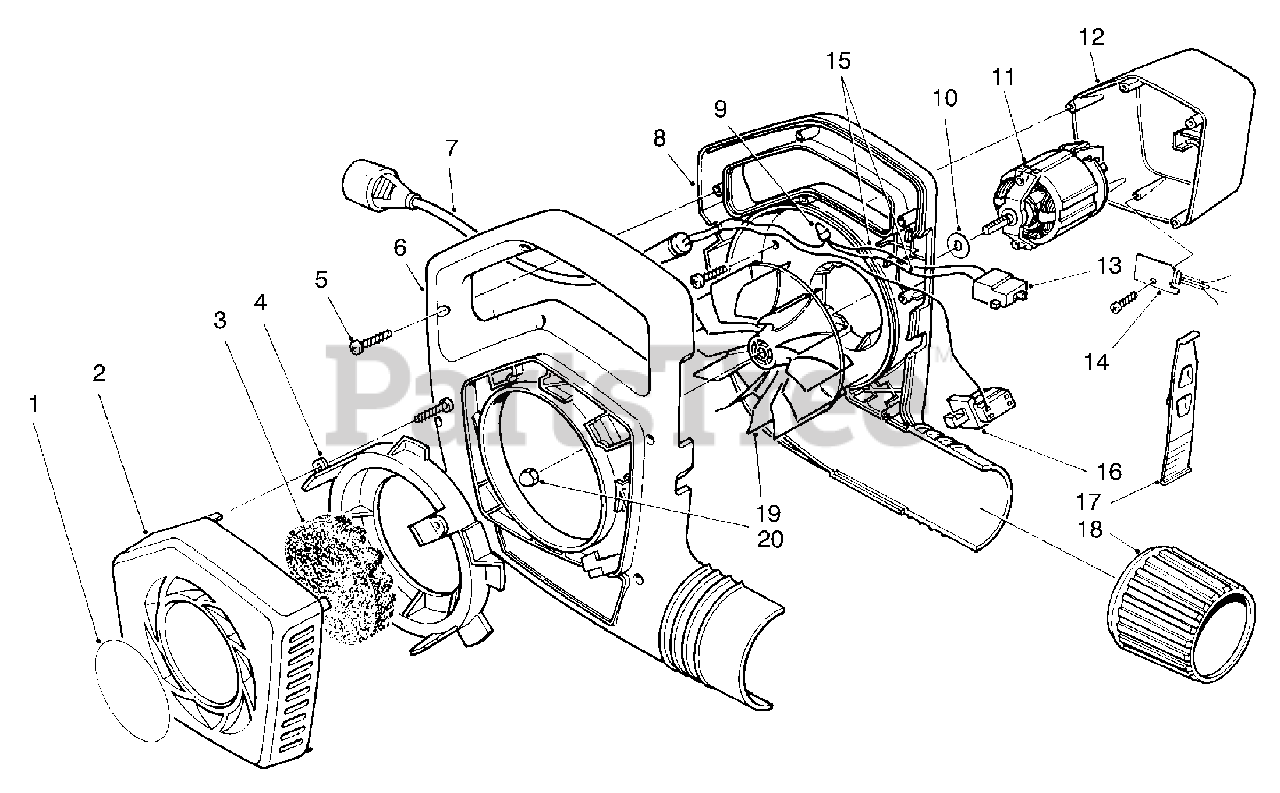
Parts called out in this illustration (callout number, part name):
1	Decal-Cover
2	Cover-Intake
3	Foam-Center
4	Ring-Coupling
5	Screw-Self Tapping
6	Housing-Blower, R.H.
7	Cord-Power Supply
8	Housing-Blower, L.H.
9	Connector-Wire
10	Washer-Impeller
11	Motor-Blower
12	Cover-Motor
13	Switch-2 Speed
14	Diode Assembly
16	Switch-Interlock
17	Switch-Cam, 2 Speed
18	Collar-Output
19	Impeller
20	Nut-Cap, Locking
